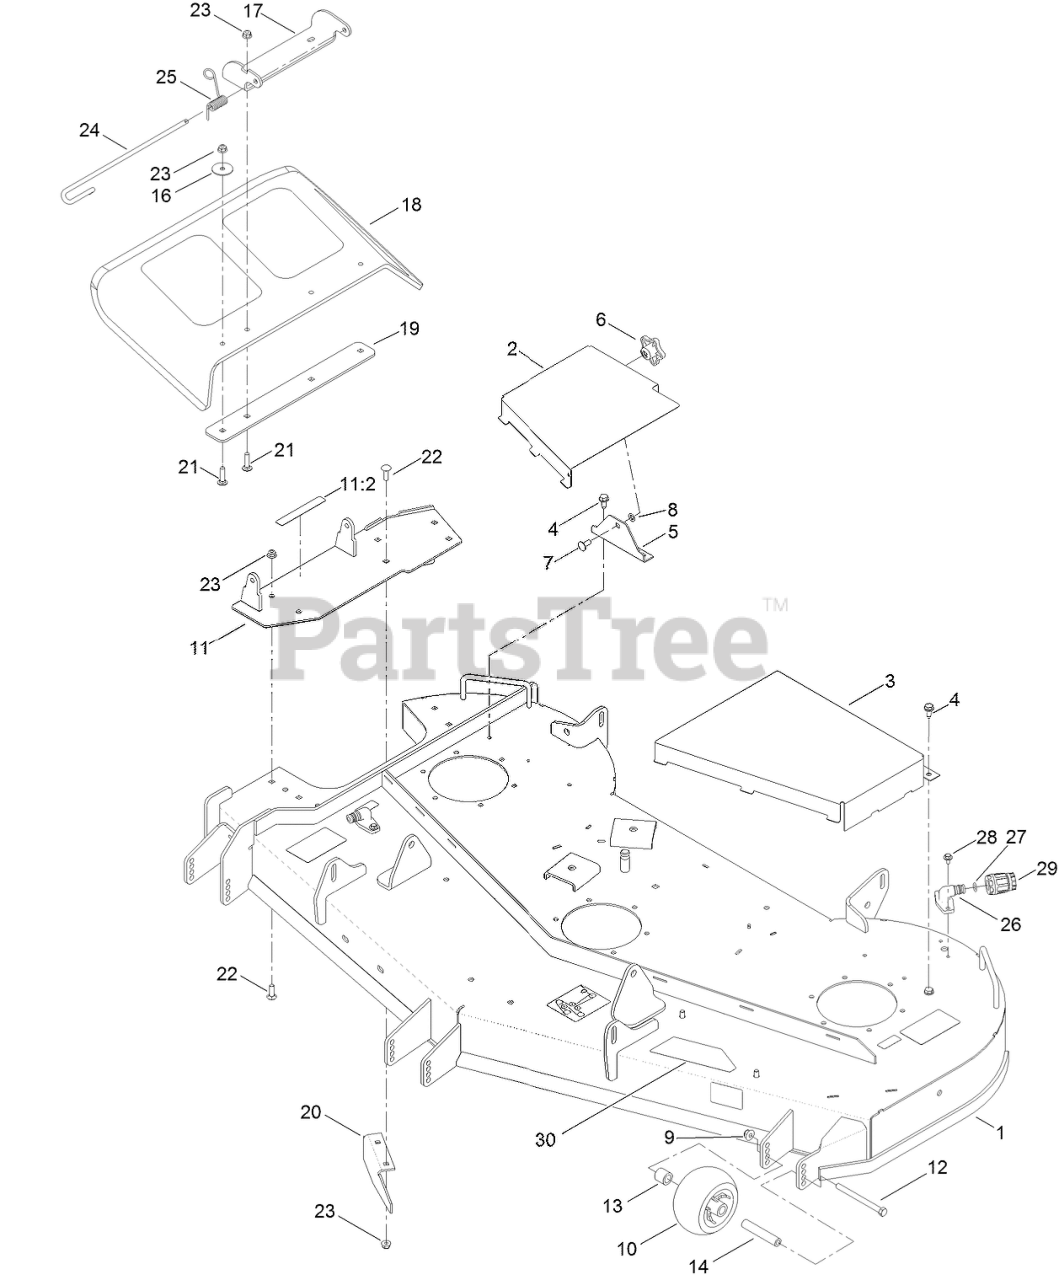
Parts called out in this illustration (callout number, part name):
1	54 INCH DECK ASM
2	COVER-BELT, RH
3	COVER-BELT, LH
4	SCREW-HWHTF
5	BRACKET-SUPPORT
6	KNOB-HANDLE
7	SCREW-CARR
8	RING-RETAINING, BOLT
9	NUT-HF, NI
10	ROLLER-SCALP, ANTI
11	PIVOT-DEFLECTOR
11:2	DECAL-DANGER
12	SCREW-HH
13	SPACER-AXLE, REAR
14	TUBE-SPANNER
16	WASHER-FLAT
17	BRACKET-DEFLECTOR, UPPER
18	DEFLECTOR
19	PLATE-DEFLECTOR
20	BAFFLE-CUTOFF
21	SCREW-CARR
22	SCREW-CARR
23	NUT-HF, NI
24	PIN-CHUTE
25	SPRING-TORSION
26	FITTING-WASHOUT
27	O-RING
28	SCREW-HHFTF
29	CONNECTOR-HOSE
